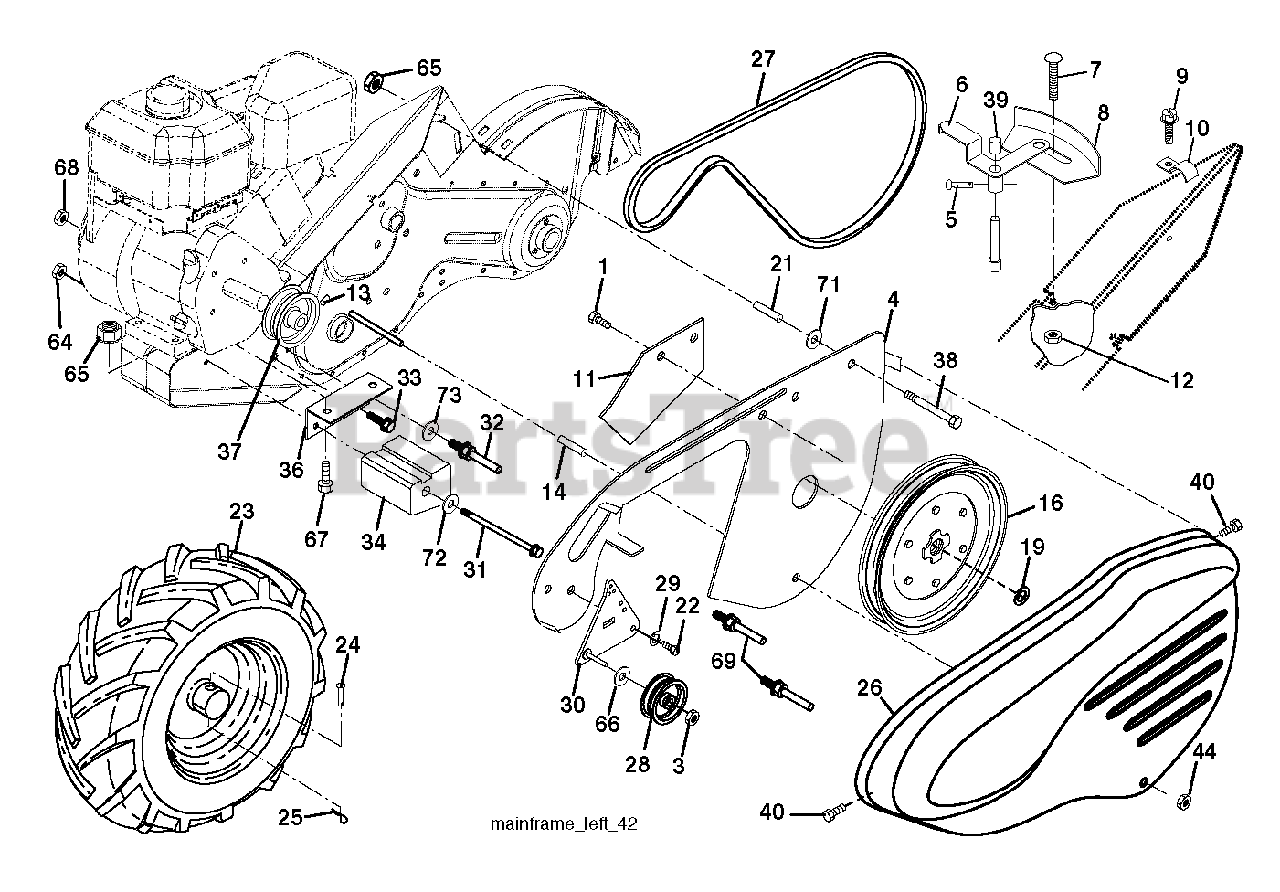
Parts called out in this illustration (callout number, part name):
1	SCREW.HEX.WASH.HD.TAPPING
3	LOCKNUT
5	PIN.SPIROL.FLARED
6	LEVER ASM CRT
8	PANEL.INDICATOR.SHIFT.BLACK
10	CLIP.PLATED
11	GUARD.RT TILLER.CRT/DRT.CE
12	NUT
13	SET SCREW
14	SPACER-SPLIT.327 X .42
16	SHEAVE, TRANSMISSION
19	RETAINING RING LT
23	WHEEL.ASM.DR,LH
26	FRAME.WELDMENT.PNT
27	V-BELT
28	PULLEY-IDLER TI
29	KLIP RING
30	BRACKET.IDLER.ASM.LONG
31	BOLT.FIN.HEX.3/8-16UNC X 11.5
32	SHIFT ARM CRT
33	BOLT
34	COUNTERWEIGHT.LH
36	BRACKET.REINFORCEMENT.LH.PNT
37	ENGINE PULLEY
39	CAP.PLUNGER.BLACK
40	SCREW.HEX.WSH.SLT.#10-24X.50
44	NUT.71038.31-18.HEX.NYLOCK
64	LOCKNUT
65	LOCKNUT-FLANGE 5/16-18
67	BOLT
69	KEEPER.BELT.ENGINE
71	SPACER SPLIT .420 X .327
73	WASHER
